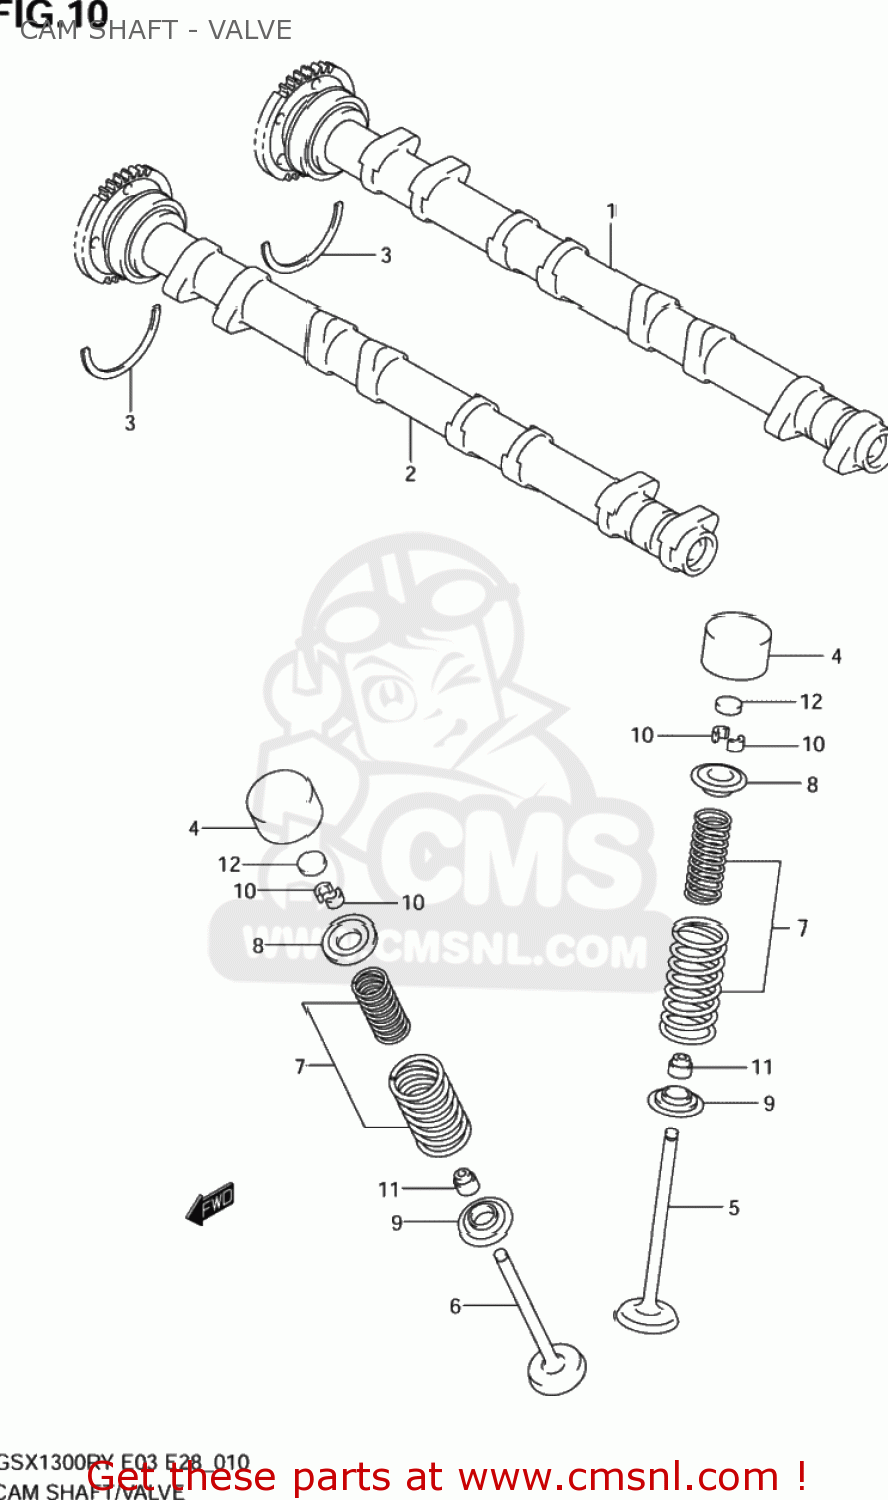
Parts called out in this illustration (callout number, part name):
1	CAMSHAFT,INTAKE
2	CAMSHAFT,EXHAUST
3	C RING
4	TAPPET
5	VALVE,INTAKE
6	VALVE,EXHAUST
7	SPRING SET,VALVE
8	RETAINER,VALVE SPRING
9	SEAT,VALVE SPRING
10	COTTER VALVE
11	SEAL,OIL(5X10X9.7)
12	SHIM,TAPPET(T:2.3)
13	SHIM SET,TAPPET
14	CASE,TAPPET SHIM
